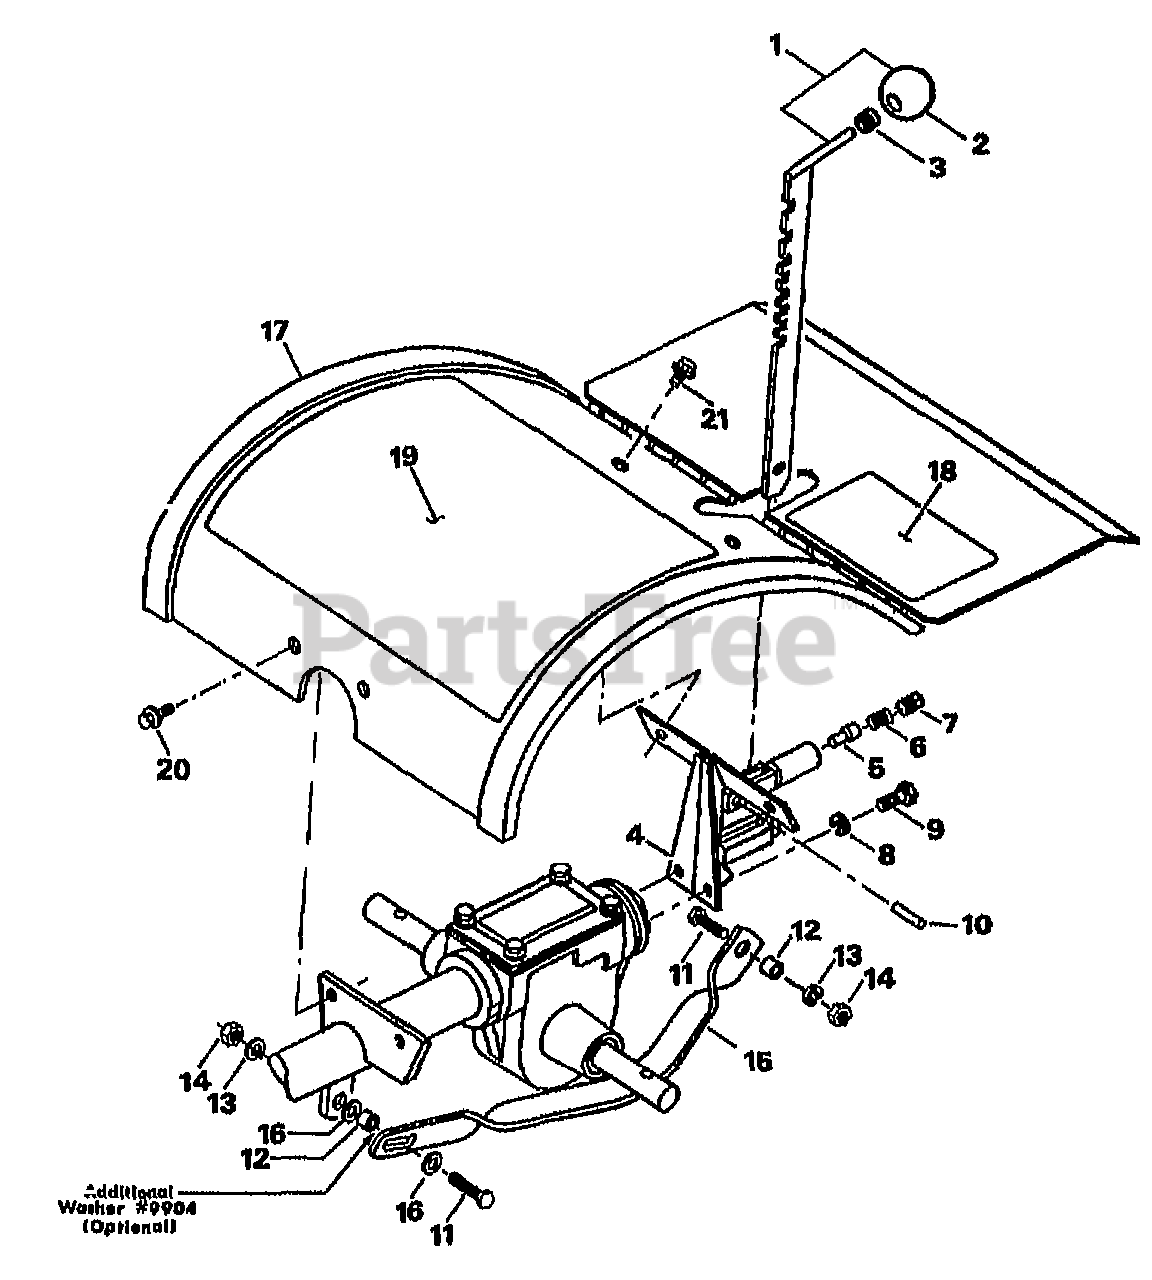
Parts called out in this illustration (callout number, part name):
1	DEPTH REGULATOR W/KNOB (Inc. 2 & 3)
2	KNOB-CONTROL
3	RING-TOLERANCE .5325 ID
4	ASSM-REAR HOOD BRKT - Depth Reg. & Tiller Hood (Inc. 10)
5	PLUNGER - Depth Reg. Locking
6	SPRING .406 X 1.25
7	PLUG-PIPE 1/4 NPT
8	WASHER-LK .312 ZP
9	SCR-HHC 5/16-18X.75 GR 5 ZP
10	PIN-SPIROL .188 X .875
11	SCR-HH 3/8-16X1.25
12	BUSHING-.5X.375X.3
13	WASHER-LK .375 @ DEPL
14	NUT-HEX 3/8-16 ZP
15	BAR-DRAG
16	WASHER-FLAT 3/8 SAE
17	ASSM-HOOD W/DECALS (Inc. 18-21)
18	DECAL-TB JR LOGO
19	DECAL-OPER INST (Operating Instructions)
20	SCR-HWH 5/16-18 X .5 STH
21	SCR-HWH 1/4-20 X .5 STH
